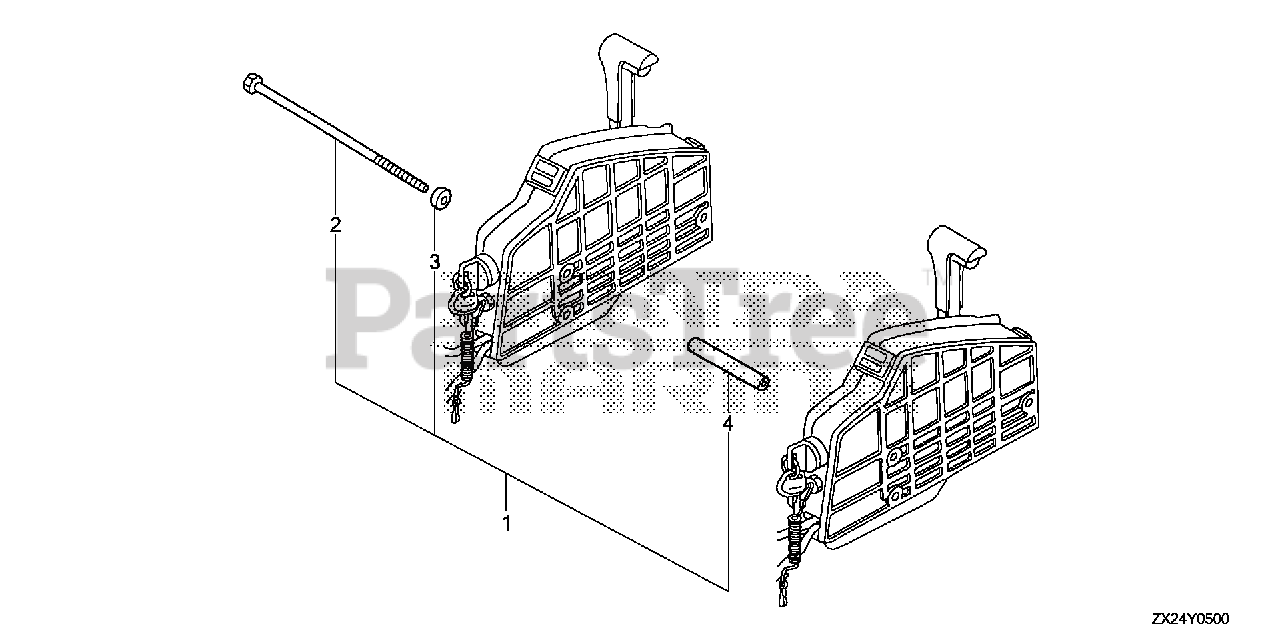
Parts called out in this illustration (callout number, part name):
1	BOLT KIT, SIDE REMOTE CONTROL
2	BOLT, SPECIAL (6X220)
3	COLLAR, DISTANCE (A)
4	COLLAR, DISTANCE (B)
